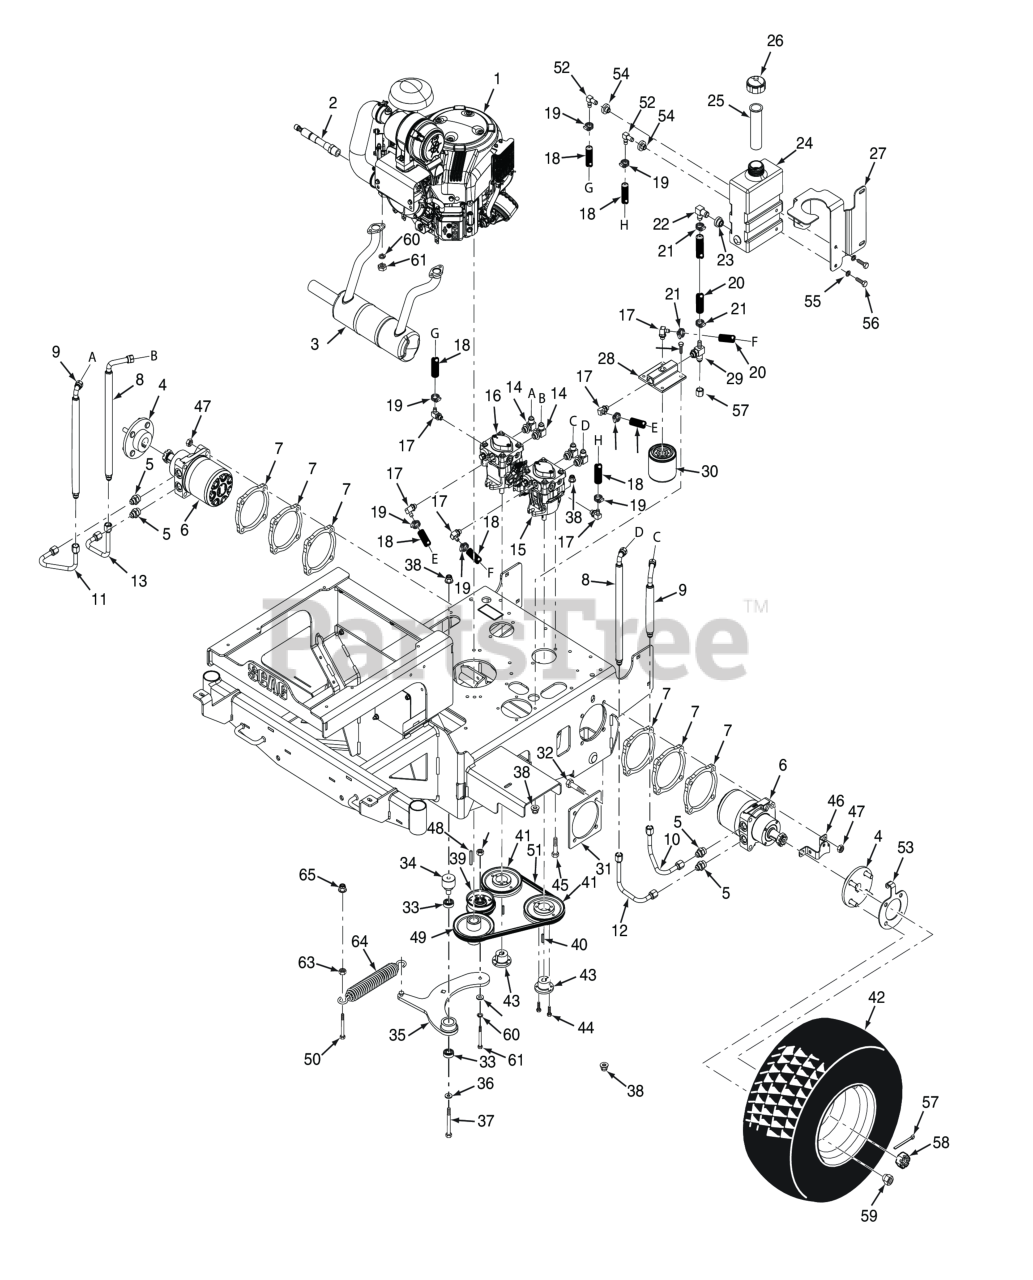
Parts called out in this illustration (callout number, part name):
1	Engine, 21 HP Briggs Vanguard
2	Hose, Oil Drain, Kohler - ECV860
3	Muffler, 21 HP BV
4	Wheel Hub Assy., SVRII
5	TUBE UNION, 3/4-16 JIC TO 7/8-14 "O" RING
6	Wheel Motor, Parker
7	Spacer, Wheel Motor
8	Hose Assy, 17.50"
9	Hose Assy, 16.25
10	Tube Assy, 1/2" LH Upper
11	Tube Assy, 1/2" RH Upper
12	Tube Assy, 1/2" LH Lower
13	Tube Assy, 1/2" RH Lower
14	Elbow, 90 Degree 3/4-16 JIC x 3/4-16 O-Ring
15	Pump, LH
16	Pump, RH
17	Elbow, 90 Degree - 9/16" O-Ring x 3/8" Hose
18	Hose, 3/8" ID - 10-1/4" Long (Order By The Inch)
19	Clamp, .69" Max. / .25" Min. Dia.
20	Hose Assembly, 1/2" ID (Oil Reservoir to Filter Base)
21	Clamp, Cable 3/4" I.D.
22	Fitting, 90 Degree - 1/2" Hose
23	Bushing, 0.78" Dia. Viton
24	Hyd. Tank Assy
25	Insert, Filler Neck
26	CAP, HYDRAULIC TANK
27	Mounting Bracket, Oil Reservoir
28	Filter Head Assembly
29	Tee, 3/8" O-Ring x JIC x 1/2" Hose
30	OIL FILTER, SPECIAL
31	Plate Weldment, Motor Backing
32	Bolt, Hex Head 1/2-13 x 4-1/4"
33	BEARINGS, BALL, NEUTRAL RETURN
34	Pivot, Idler
35	Idler Arm Assembly
36	Flatwasher, 3/8 (.391 x .938 x .105 HD) Grade 8
37	Bolt, Hex Head 3/8- 16 x 3.50 - Stainless Steel
38	Nut, Flange Elastic Stop 3/8 - 16 - Stainless Steel
39	Pulley, 3-1/2" Dia.
40	KEY, 5 MM X 5 MM X 25 MM
41	Pulley, 5.45 OD - Tapered Bore"
42	Wheel Assembly, 20 x 12 - 10
43	Hub, Tapered, 15mm Bore
44	Bolt, Hex Head 1/4-20 x 1" Grade 8 Black
45	Bolt, Hex Head 3/8 - 16 x 1.50 - Stainless Steel
46	Plate, Speed Sensor
47	Locknut, Hex 1/2-13 Center Lock
48	Key, 1/4 x 1/4 x 2.0"
49	Pulley 5.45 OD x 1.125 Bore
50	Bolt, Hex Head 3/8-16 x 2-1/4" - Stainless Steel
51	Belt, Pump Drive
52	Elbow, 90 Degree, 9/16-18 JIC x 9/16 O-Ring
53	Plate, Hub Magnet Holder
54	Bushing, 0.56" Dia. Viton
55	Bolt, Hex 5/16 - 18 x .75 - Stainless Steel
56	Washer, Lock 5/16 Spring - Stainless Steel
57	Pin, Cotter 9/16" x 1-1/2"
58	Nut, Hex Castle 1.0-20 UNEF
59	Wheel Nut, 1/2-20 x 13/16
60	Bolt, Hex Head 7/16-20 x 1.25"
61	Flatwasher, 7/16-.469 x 1.750 x 1/4"
62	Flatwasher, 7/16-.469 x 1.75 x .25 (48, 52)
63	Nut, 3/8 - 16 - Stainless Steel
64	Spring, PTO (Gasoline Engines)
65	Nut, Flange Elastic Stop 3/8 - 16 - Stainless Steel
